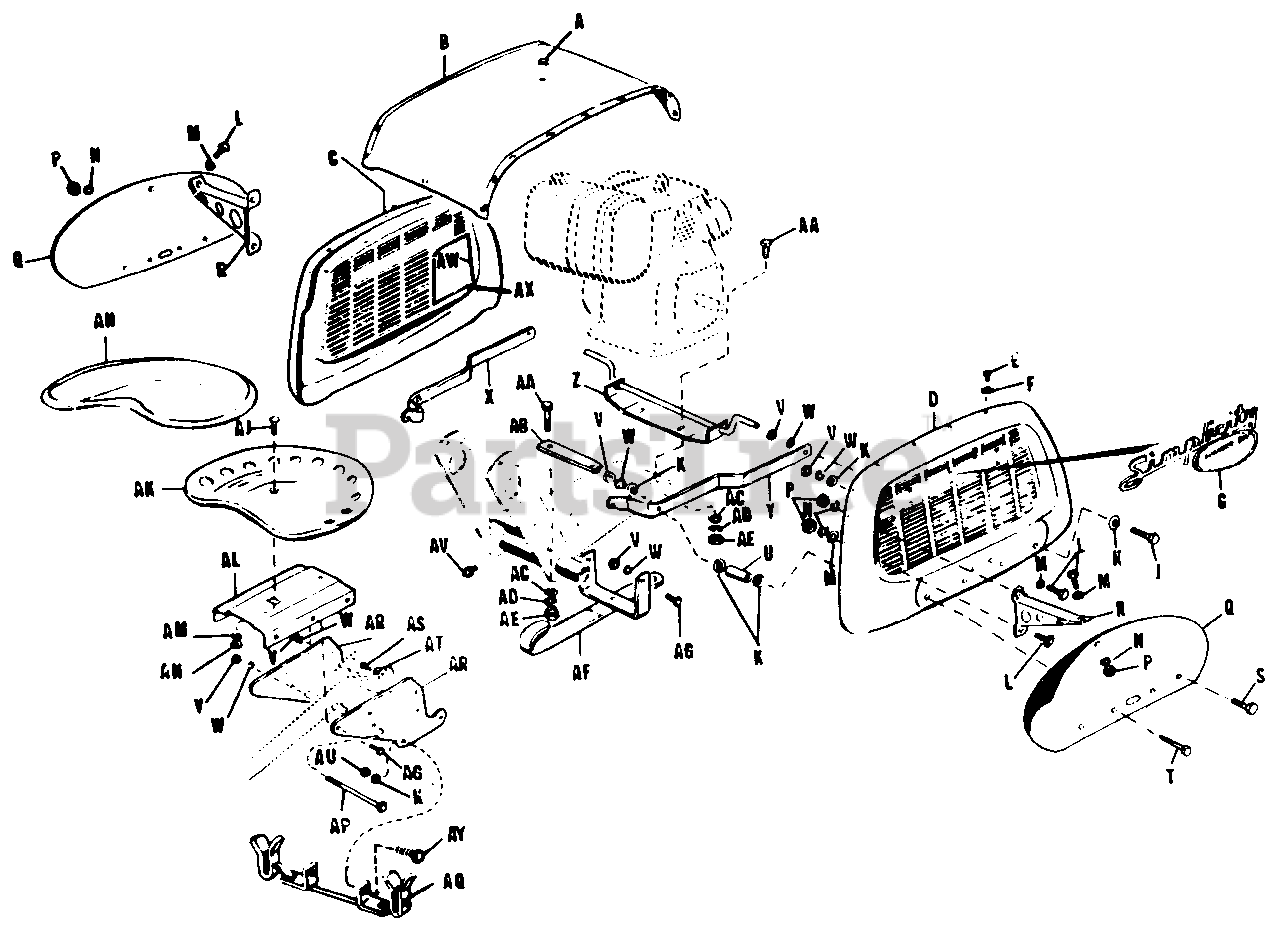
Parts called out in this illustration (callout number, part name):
A	Plug Button
B	Panel, Top
C	Panel, Side, R.H.
D	Panel, Side, L.H.
E	Screw, #10 x 1/2
F	Speed Nut
G	Emblem, Simplicity-Wonder-Boy "600"
J	Capscrew, Hex Hd., 3/8-16 x 1 1/4
K	Washer, Lock
L	Capscrew, Hex Hd., 1/4-20 x 1/2
M	Washer, Plain, 1/4
N	Lockwasher, 1/4
P	Nut, Full Hex, 1/4-20
R	Brace, Fender
S	Capscrew, Hex Hd., 3/8-16 x 5/8
T	Capscrew, Hex Hd., 3/8-16 x 2
U	Spacer, Latch
V	Nut, Full Hex, 3/8-16
W	Washer, Lock, 3/8
X	Latch Arm, R.H.
Y	Latch Arm, L.H.
Z	Bracket Assembly, Pivot
AA	Capscrew, Hex Hd., 5/16-18 x 1 3/4
AB	Spacer, Engine
AC	Washer, Plain, 5/16
AD	Washer, Lock, 5/16
AE	Nut, Full Hex, 5/16-18
AF	Draw Bar Assembly
AG	Capscrew, Hex Hd., 3/8-16 x 1
AH	Pad, Seat
AJ	Carriage Bolt, 1/2-13 x 1
AL	Support, Seat
AM	Washer, Lock, 1/2
AN	Nut, Full Hex, 1/2-13
AP	Bolt, Sq. Hd. Machine, 3/8-16 x 6
AQ	Catch Assembly
AR	Side Plate
AS	Capscrew, Hex Hd., 7/16-20 x 3/4
AT	Washer, Lock, 7/16 Internal Shakeproof
AU	Nut, Full Hex
AV	Grease Fitting, Alemite #1637
AW	Trim, Side Panel
AX	Clip, for trim
AY	Cap Screw
